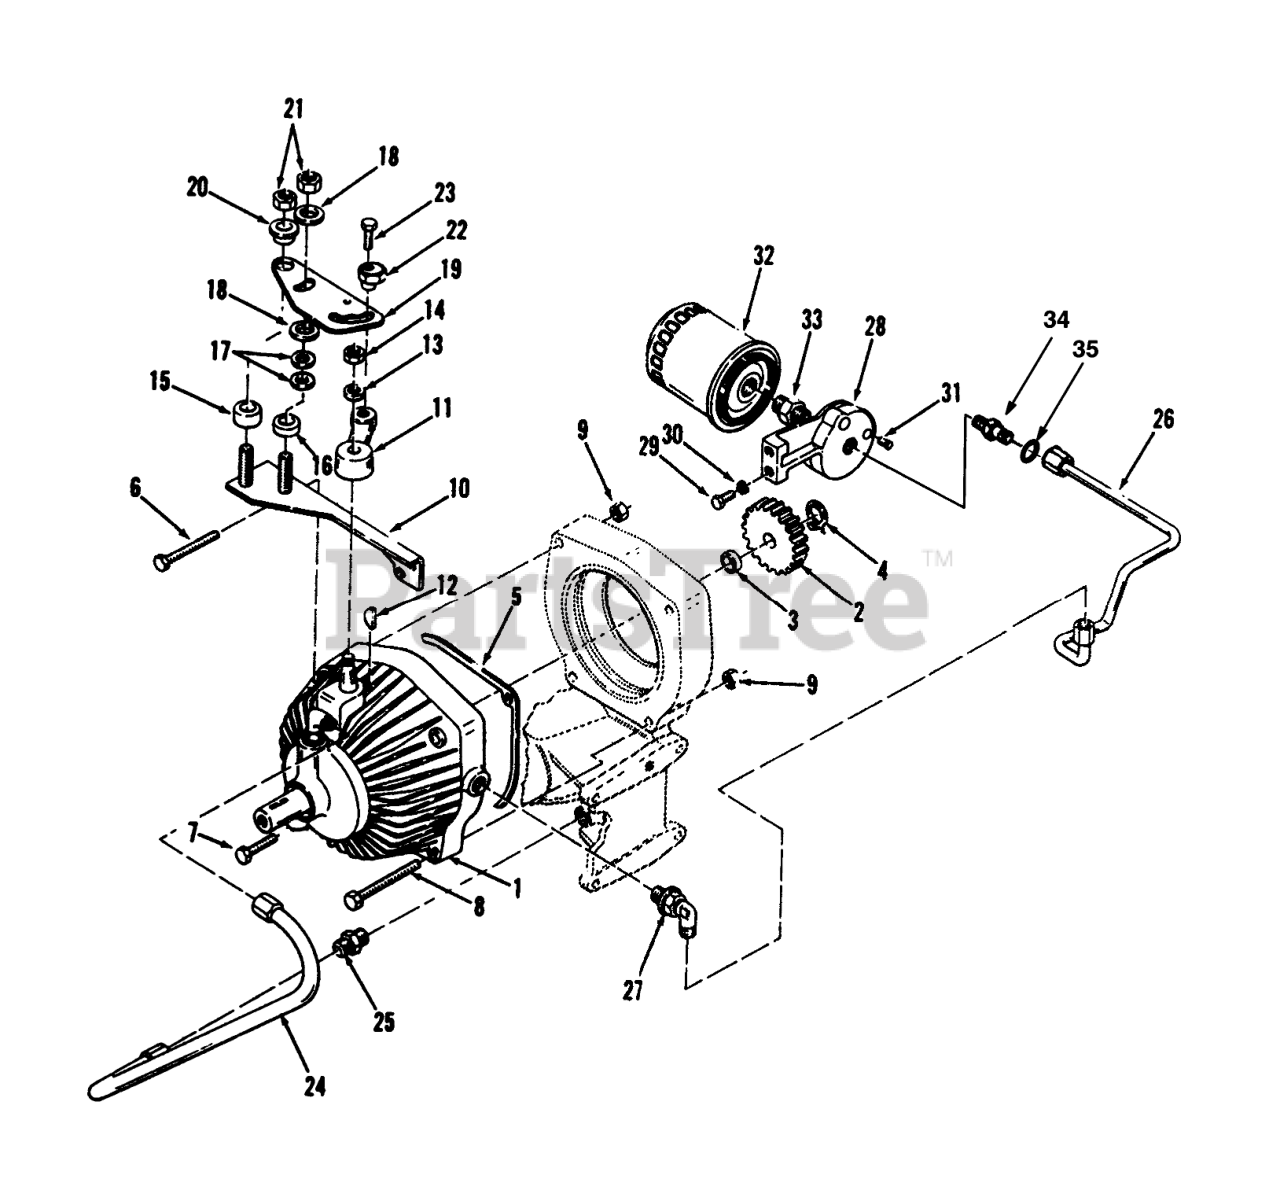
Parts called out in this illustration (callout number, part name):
1	Pump & Motor
2	GEAR 20 TEETH DRIVE
3	SPACER GEAR
4	RING-SNAP, EXTERNAL
5	GASKET
6	SCREW-HH
7	SCREW-HH
8	SCREW-HH
9	NUT-LOCK, NI
10	ASSY-PLATE B
11	ARM-SPEED CONTROLB
12	KEY-WOODRUFF
13	NUT-LOCK, NI
14	NUT-LOCK, NI
15	SPACER-PIVOT
16	SPACER-FRICTION
17	WASHER-SPRING DISC
18	FRICTION WASHER
19	CAM-SPEED CONTROL (NS)
20	CAM-SPACER
23	SCREW-HH
24	ASSY-TUBE SUCTION
25	FITTING-TUBE
26	ASS'Y-TUBE FILTER
27	ELBOW
28	BASE-FILTER
29	SCREW-HH
30	WASHER-LOCK
32	OIL FILTER ASM
33	FITTING
34	FITTING
35	0-Ring
